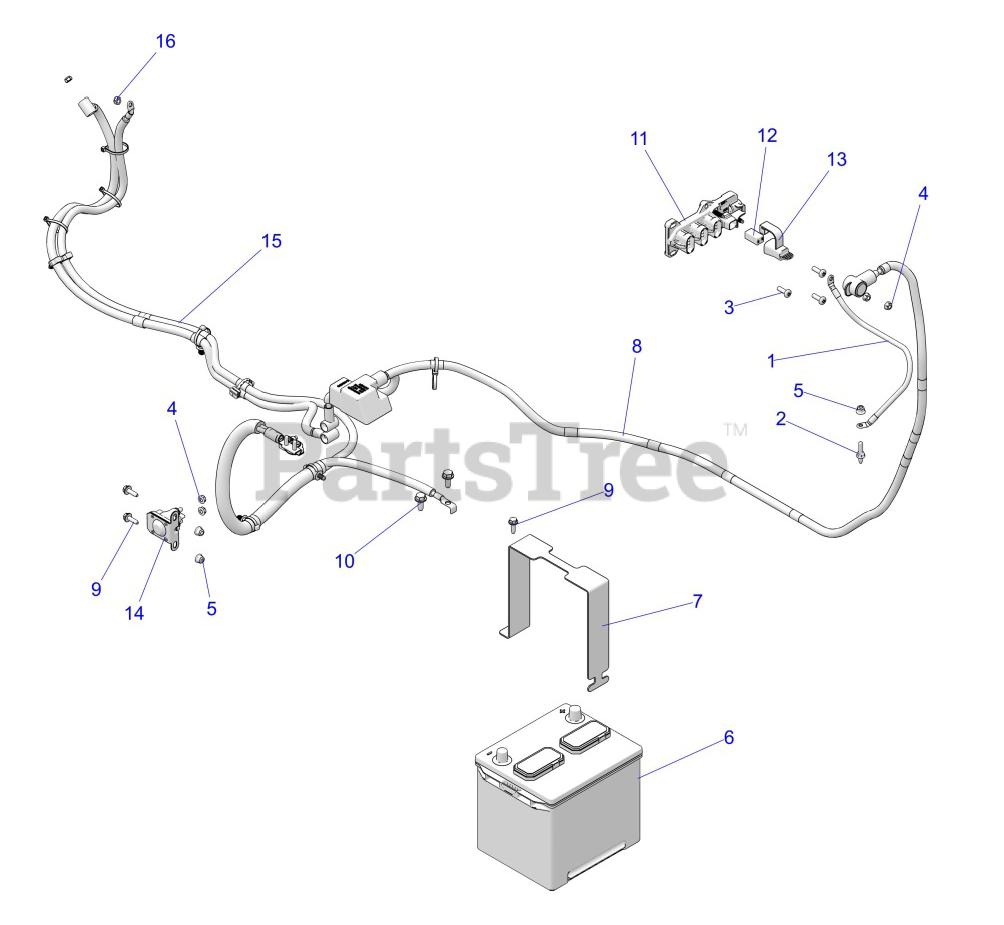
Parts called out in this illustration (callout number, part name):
1	CABLE-GROUND,ENG,BAT,CHAS
2	STUD-M6X1.0X19-M6 TAPTITE
3	SCR-TXPH-#14 X .75 HI-LO RIE
4	NUT-HXFLGHD,M6,SERRATED
5	NUT-M6 FLANGE,NYLOK
6	BATTERY, 575 CCA, FLOODED, FILLED
7	BRKT-BATTERY STRAP GALV
8	CABLE-BATTERY TO SOLENOID
9	SCR-M6X1.0X20,HXHD,FLG,TDFM,BL
10	SCR-HXFL-M8X1.25X20 TAP ZY3
11	BLOCK-TERMINAL,3 POS
12	FUSE-CARTRIDGE,25A
13	COVER,TB,25A,JCASE
14	SOLENOID-STARTER,SEALED
15	CABLE-START,TO,SOLENOID,GAS
16	NUT,NYLOK(10)
